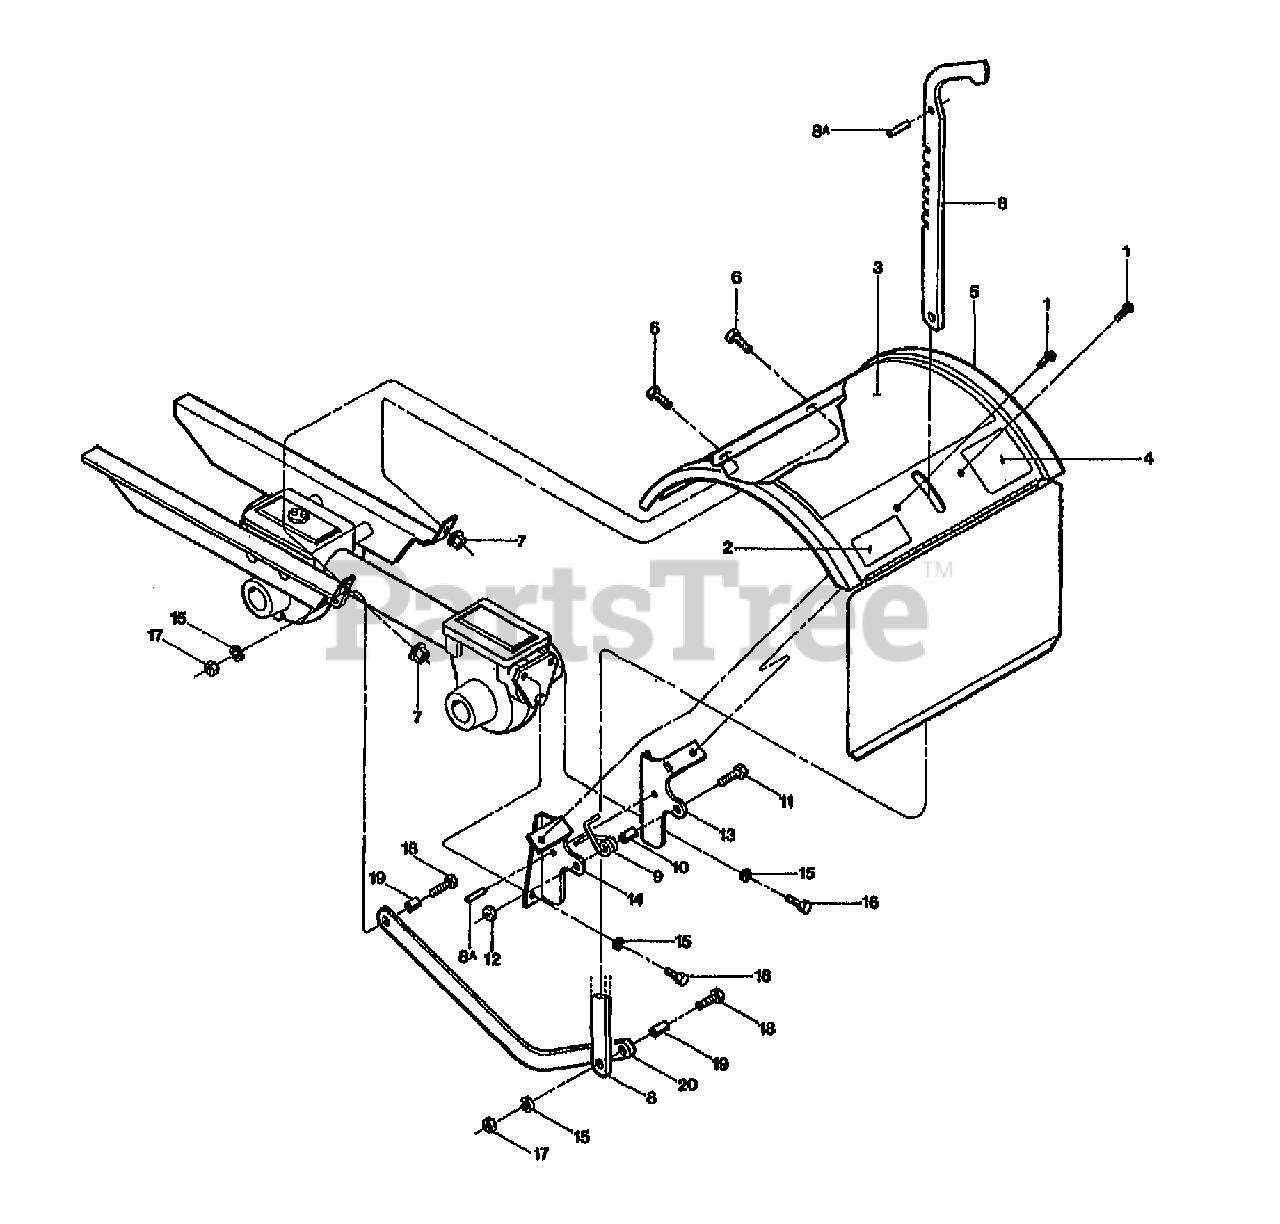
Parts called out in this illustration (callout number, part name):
1	SCR-HWH 1/4-20 X .5 STH
2	DECAL-LOGO TUFFY HOOD
3	DECAL-HOOD TUFFY (OPERATING & SAFETY INSTRUCTIONS)
4	DECAL-TINE WARN SM FRAME
5	HOOD W/DECALS PNT (INCL. TINE FLAP, 55054, 55051, & 20814)
6	SCR-HH 5/16-18X.5 GD5 YEL
7	NUT-HFLK 5/16-18 ZP
8	DEPTH REG-W/PIN PNT
8A	PIN-ROLL .25 X 1
9	SPRING-TORSION
10	SPACER-.250X.343X.375
11	SCR-HH 1/4-20X1.0
12	NUT-LK 1/4-20
13	BRKT-HOOD RIGHT PNT
14	BRKT-HOOD LEFT PNT
15	WASHER-LK .312 ZP
16	SCR-HH 5/16-18X1.0 G5 ZP
17	NUT-HEX 5/16-18 ZP
18	SCR-HH 5/16-18X1.25 G5ZP
19	BUSHING-.438X.323X.4
20	DRAG BAR-TUFFY PNT
